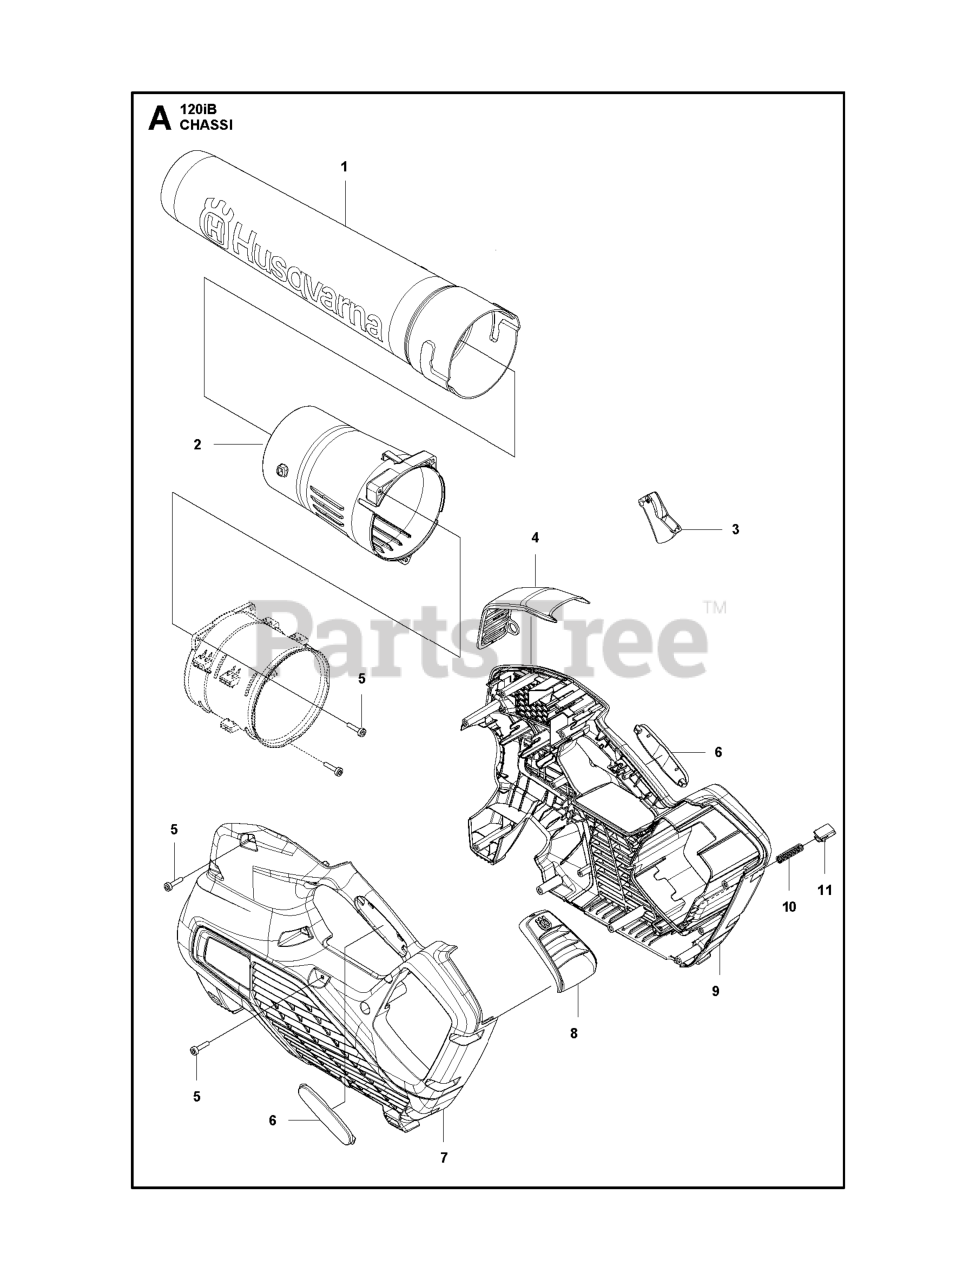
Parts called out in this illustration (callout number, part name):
1	NOZZLE BLOWER 320IB
2	TUBE FAN SYSTEM
3	THROTTLE CONTROL
5	SCREW ITXSCT PW4.2X18 10.9 ZN
6	HANDLE INSERT GREY
7	HOUSING LEFT
9	HOUSING RIGHT
10	SPRING PUSH OUT
11	PUSH BUTTON
